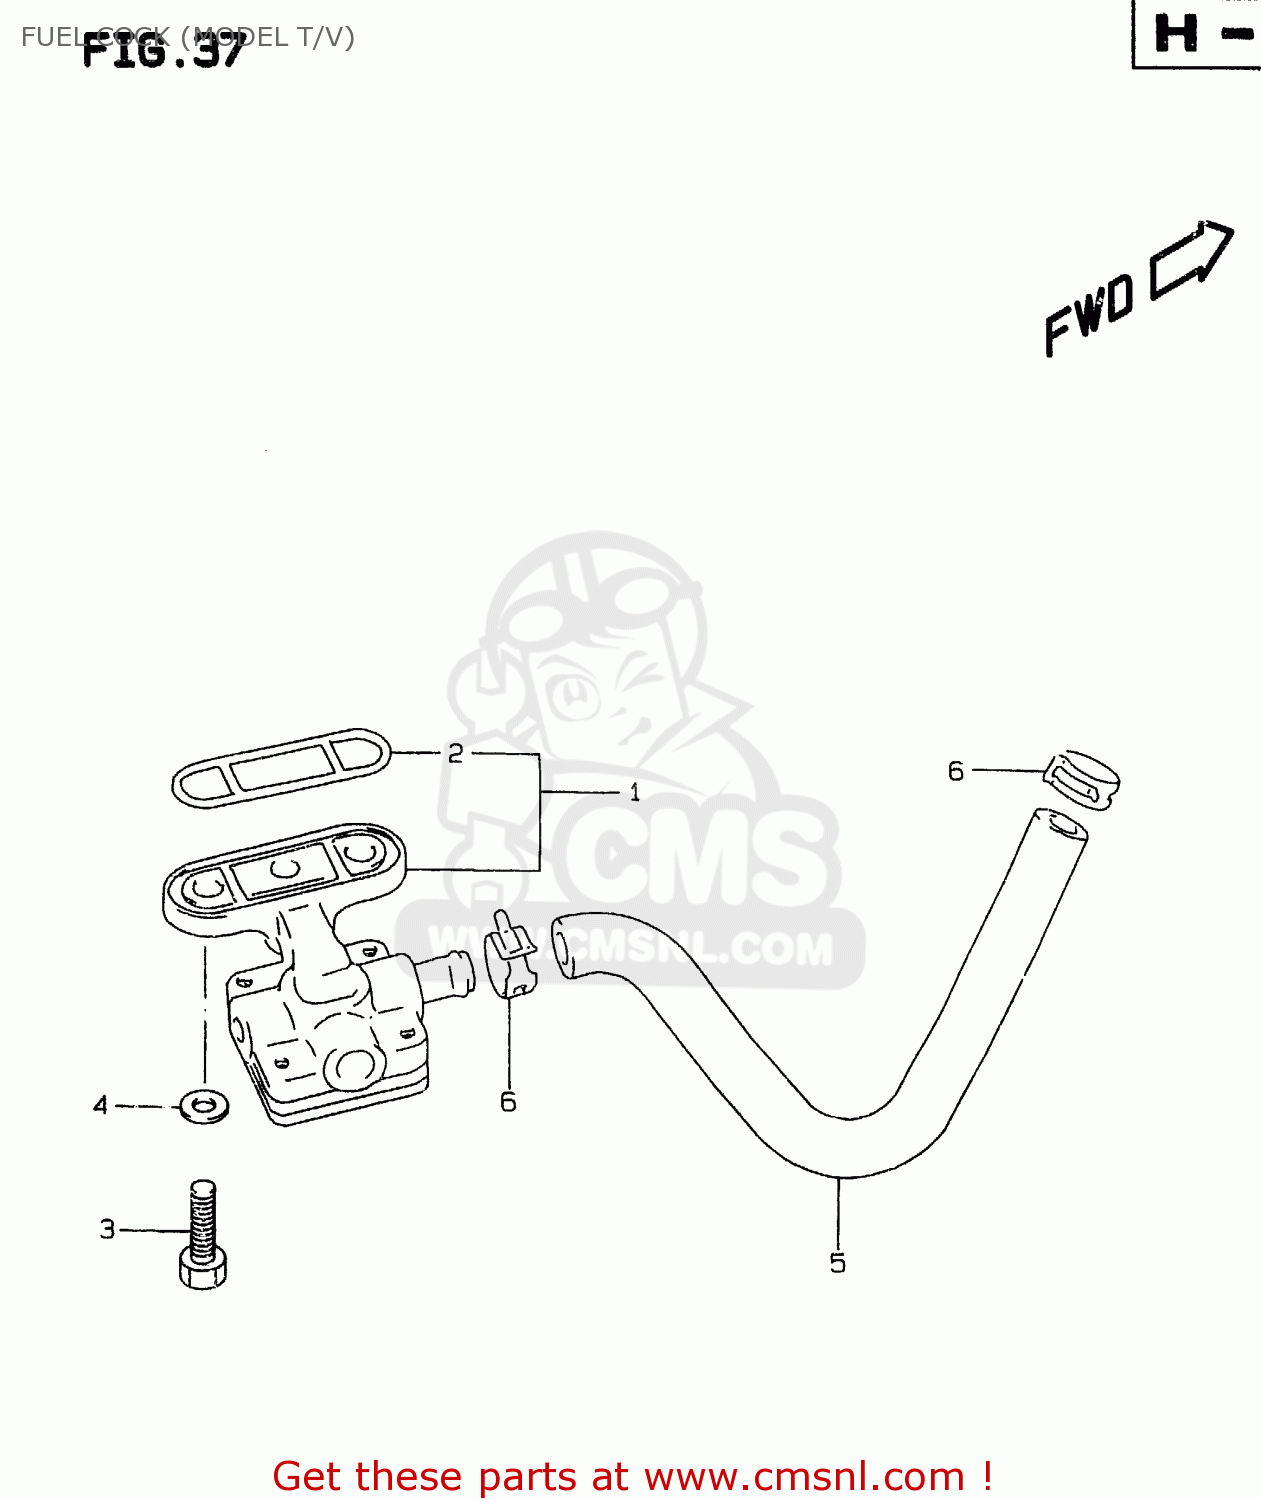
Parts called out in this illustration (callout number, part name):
1	COCK ASSEMBLY,FUEL
2	O RING,JOINT
3	BOLT(6X20)
4	GASKET(6.4X11.5X0.8) (NAS)
5	HOSE(7X12X600)
6	CLIP
